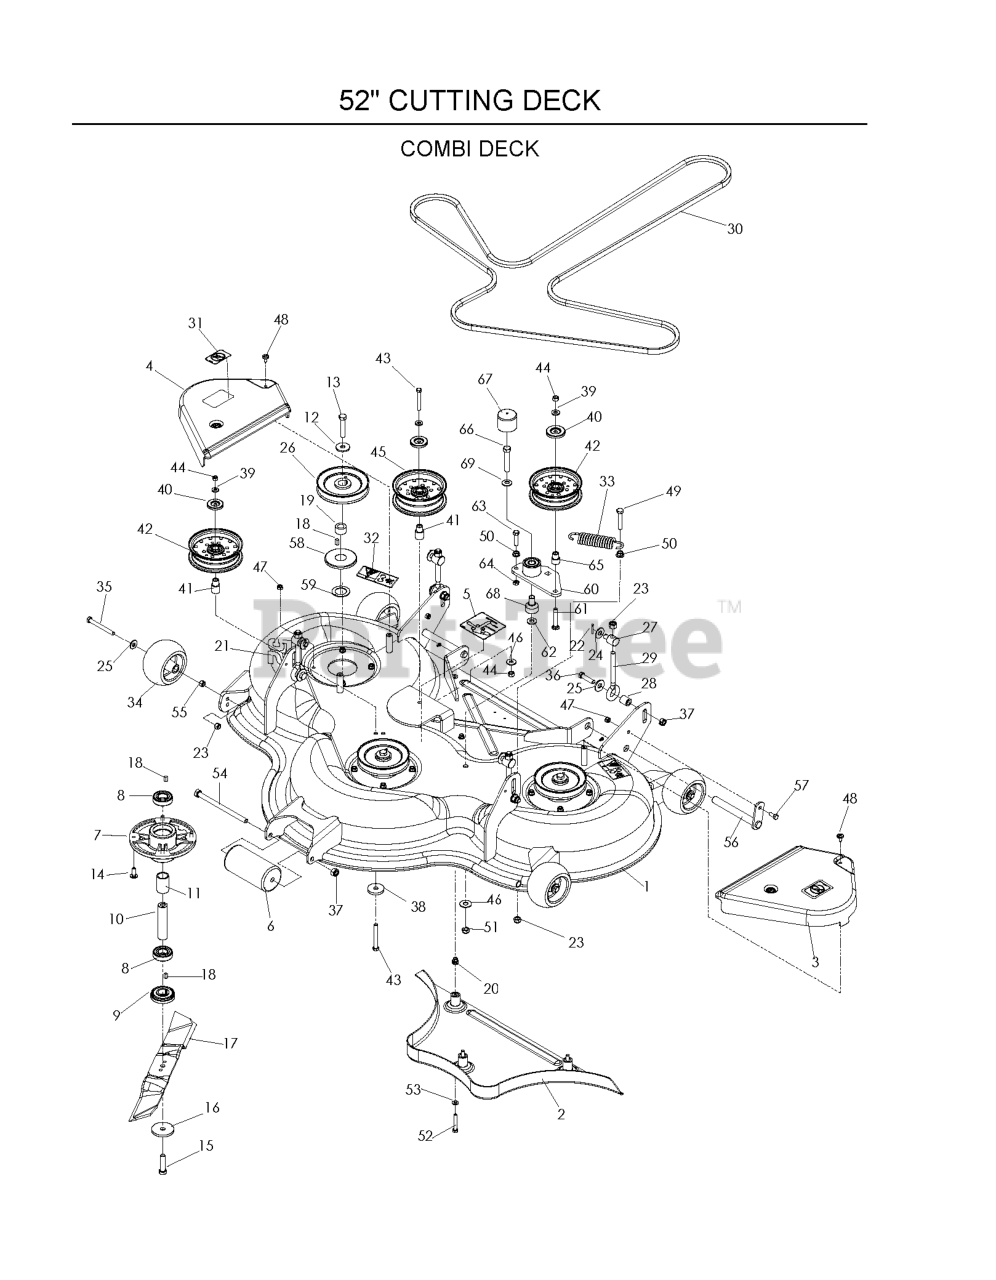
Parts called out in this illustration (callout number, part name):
1	DECK W/DECALS, 52L HUS
3	BELT SHIELD LT
4	BELT SHIELD RT
5	DECAL, BELT ROUTING
6	ROLLER
7	BEARING HOUSING
8	BALL BEARING
9	BUSHING, BLADE
12	WASHER-.533IDX1.37OD
13	HCS M12 X 1.75 X 60 GR5 ZD
14	RHSNB 5/16C X 1
15	HCS M12 X 1.75 X 50 GR8.8 ZD
17	BLADE REAR DISCHARGE/MULCH C13
19	KEY RETAINER
20	BLIND RIVET NUT
22	PIN COTTER 1/8 X 1 ZD
23	NUT 1/2-13 HEX NYLOC ZD
24	WASHER 1/2 FLAT
25	WASH USS FLAT 1/2
26	PULLEY, 52
30	BELT, DECK 52 COMBI/60 GRIZZY
31	DECAL, NO STEP
32	DECAL, BELT DRIVE
34	GAUGE WHEEL
35	HCS 1/2-13 X 4 GR 5 ZD
36	HCS 7/16 - 14 X 1 3/4
37	NUT 7/16C CENTERLOCK
38	SPINDLE WASHER
39	WASHER, 3/8 THICK
40	DUST SHIELD
41	IDLER BUSHING
42	IDLER PULLEY
43	SCREW 3/8C X 2 3/4 HEX CAP
44	NUT 3/8-16 NYLOC
45	IDLER PULLEY (TALL)
46	WASHER 3/8 FLAT
47	5/16-18 NYLOC FLANGE NUT
48	SCREW 1/4 X 5/8
49	HCS 3/8C X 2
50	NUT 3/8C WHIZ
51	NUT HEX 3/8-16 NYLON, THIN
52	HCS M8 X 1.25 X 50 GR8.8 ZD
53	FLAT WASHER 5/16 SAE
54	HCS 7/16-14 X 7 GR5 ZD
55	NUT HEX 1/2
56	PIN, STRUT, WELDMENT
57	HCS 5/16C X 1
58	BOTTOM DUST CAP
59	WASHER-1.06IDX1.63ODX.06
60	ARM-IDLER W/BRG
61	CARRIAGE BOLT 3/8-16 X
62	WASHER 1/2" FLAT
63	HCS 3/8-16 X 1-1/2
64	NUT 3/8-16 HEX JAM
65	BUSHING, IDLER
66	HCS 1/2C X 2 3/4
67	CAP, VINYL
68	PIVOT, BEARING
69	CONTACT BELLSPR 1/2
